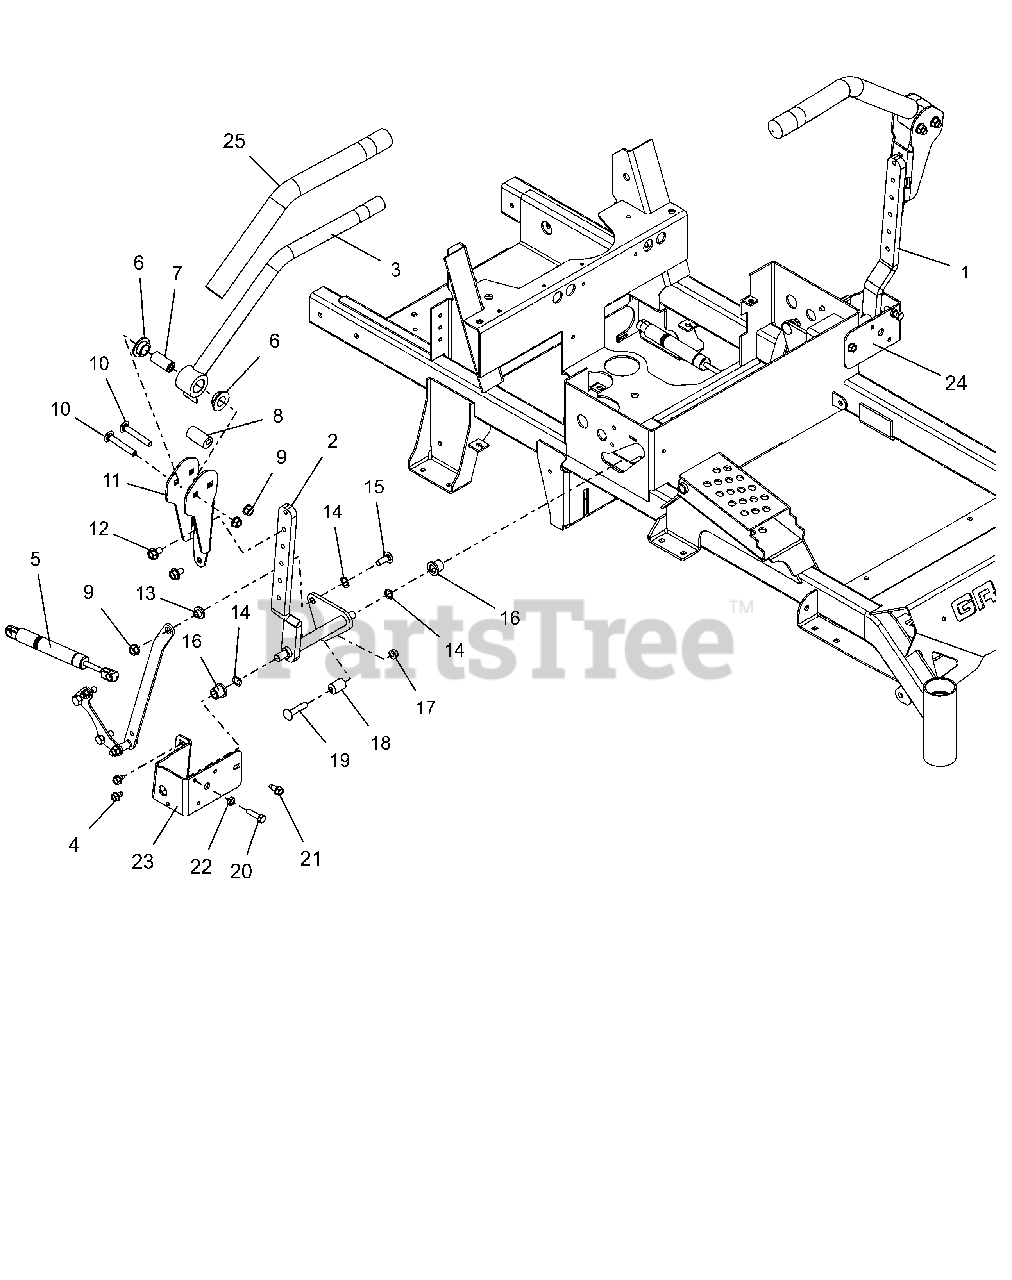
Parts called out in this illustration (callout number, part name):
1	WLDMT, LH COMPACT CONTROL ARM
2	WLDMT, RH COMPACT CONTROL ARM
3	KIT, CONTROL HANDLES
4	SCR,TAP .312-18X.50 HWH TR ZCC
5	DAMPER, CONTROL
6	BSHG-FLG .762X1.48X.44 NYL
7	SPACER, STEERING ARM
8	BSHG, ECCENTRIC.406X.875X1.625
9	NUT-LK-CTR-FLG .375-16 GF ZCC
10	BLT, RHSSN.38-16X2.50 G5 ZCC
11	ADJ UPPER CONTROL ARM BRKT-BLK
12	BLT, SCRHFWH .375-16X.625 YWZC
13	BSHG-FLG .385X.500X.875X.406
14	WAVE WASHER .531X.781X.125FH
15	BLT,RHSSN .38-16X1.00 G5 ZCC
16	BHSG-FLG .500X.750X.750X.125
17	NUT,LK-CTR-FLG .31-18 GF ZCC
18	ECCENTRIC
19	BTL,RHSSN .375-16 X 1.75 G5 ZCC
20	BLT, HEX .31-18X1.25 G5 ZCC
21	SCR,TAP .312-18X.75 HWH TR ZCC
22	NUT-JAM .312-18 G2 ZCC
23	STOP, RH COMPACT DRIVE CONTROL
24	WLDMT, COMPACT PRO FRAME
25	GRIP, HANDLEBAR
